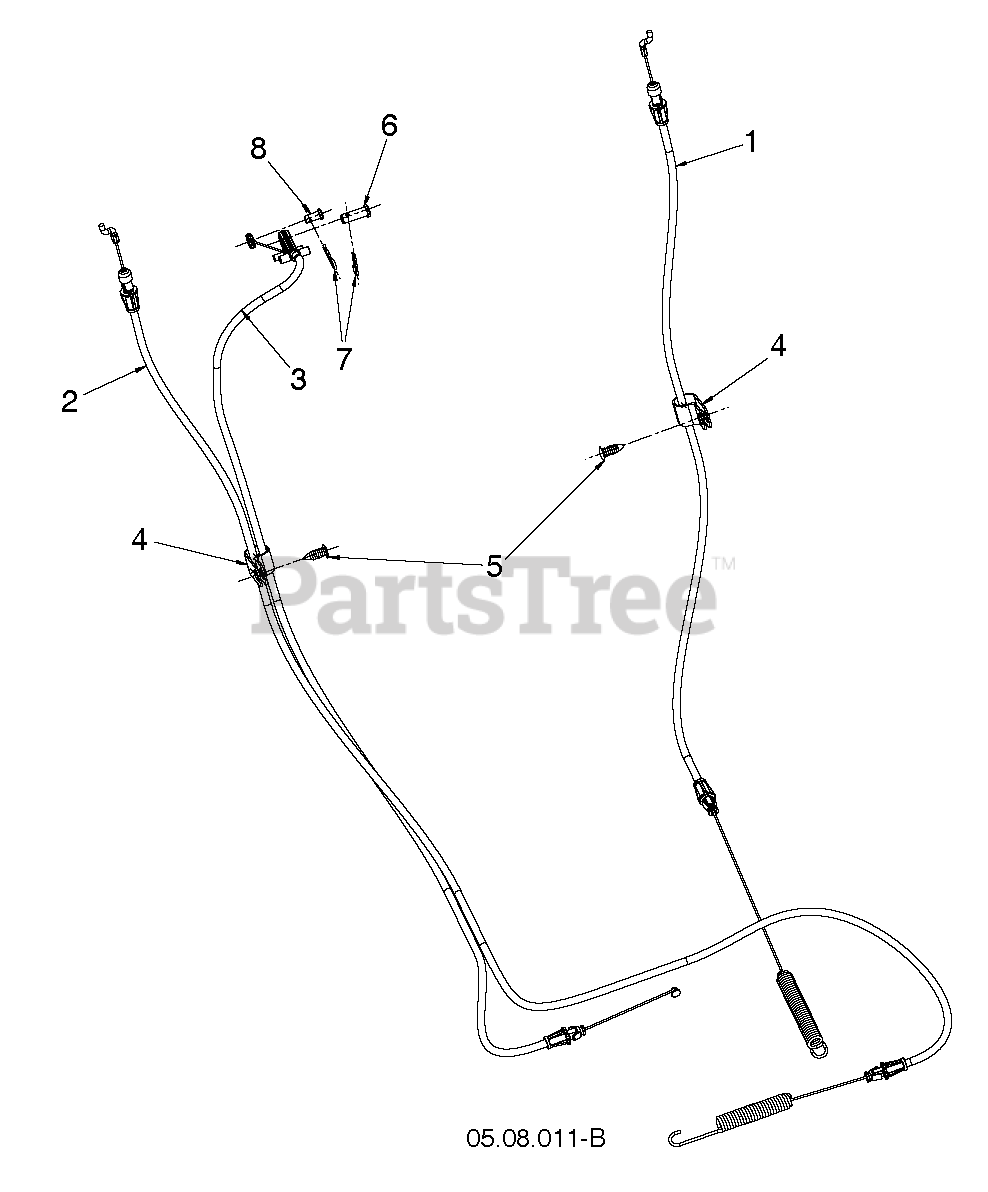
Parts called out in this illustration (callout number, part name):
2	Auger Control Cable
3	Speed Control Cable, DSST OPP
4	CLIP.CABLE.BLK
5	FASTENER.PUSH.O.250X0.783
6	Clevis Pin, 5/16 X .875
8	Clevis Pin, .25 X .31
